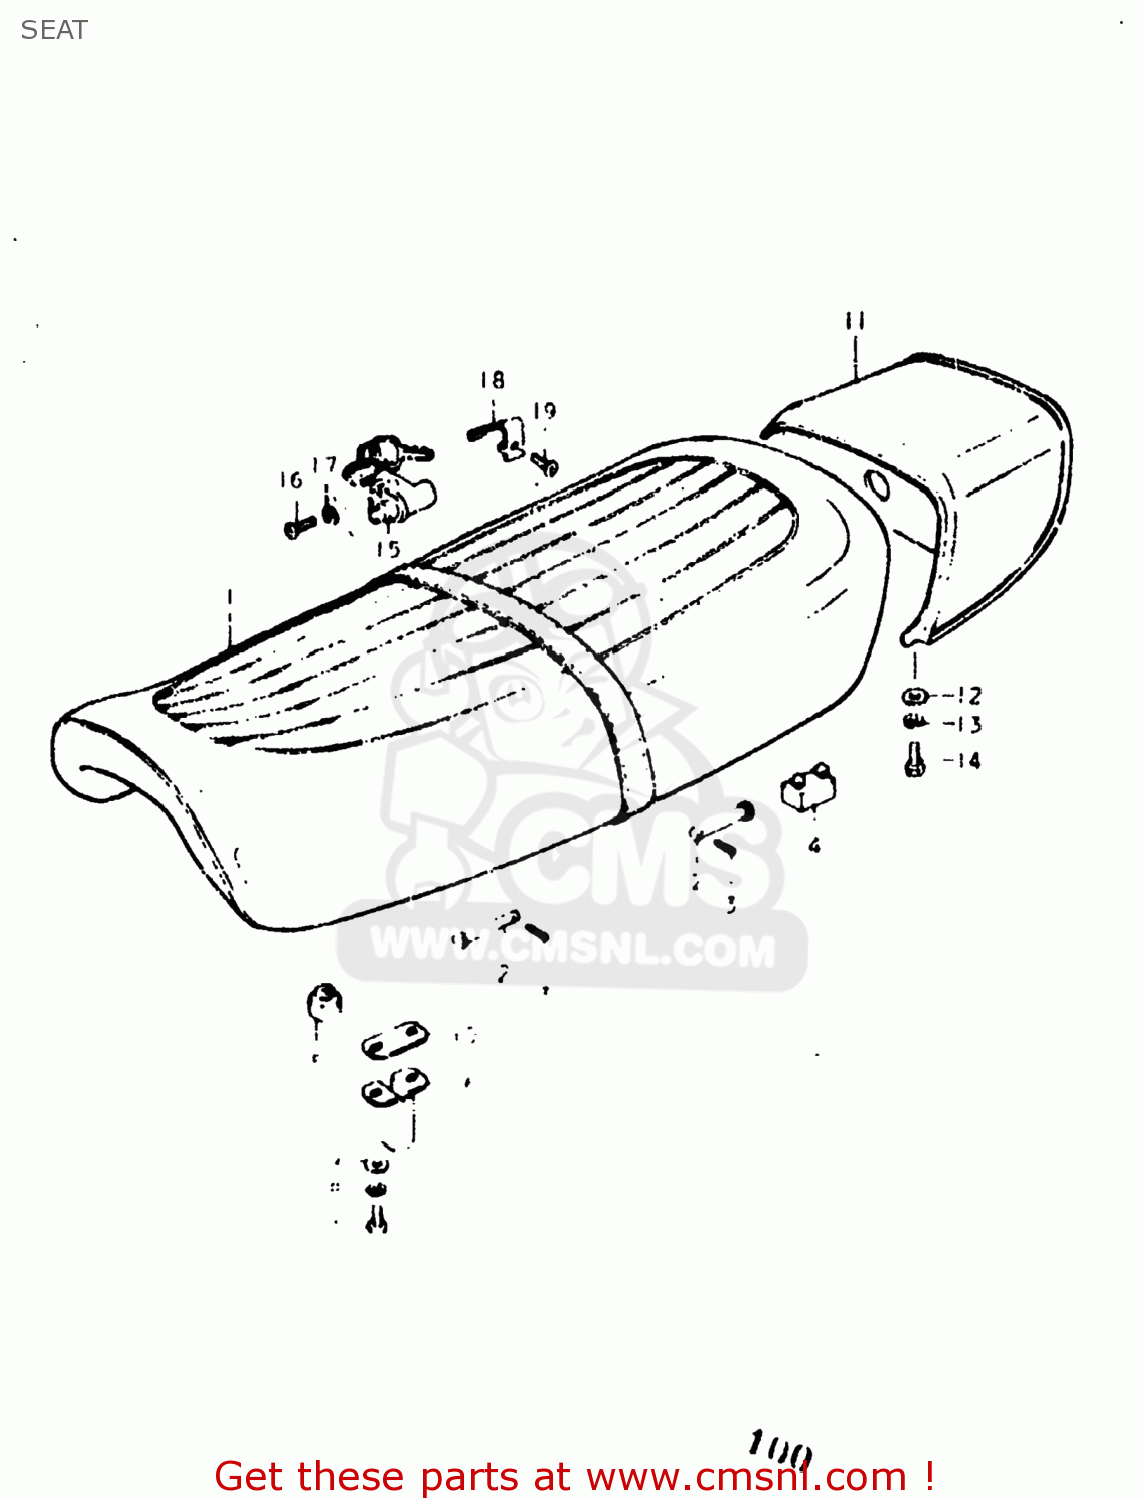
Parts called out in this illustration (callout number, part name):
1	SEAT ASSEMBLY
2	PIN
3	PIN
4	CUSHION
5	CUSHION(11.5X22X20)
6	STRIKER,SEAT LOCK
7	SCREW 6X12
8	LOCK WASHER
9	WASHER
10	SHIM,SEAT LOCK STRIKER
11	COVER,SEAT TAIL
12	WASHER
13	LOCK WASHER
14	BOLT
15	LOCK ASSEMBLY,SEAT
16	Screw
17	LOCK WASHER
18	SPRING,HELMET HOLDER
